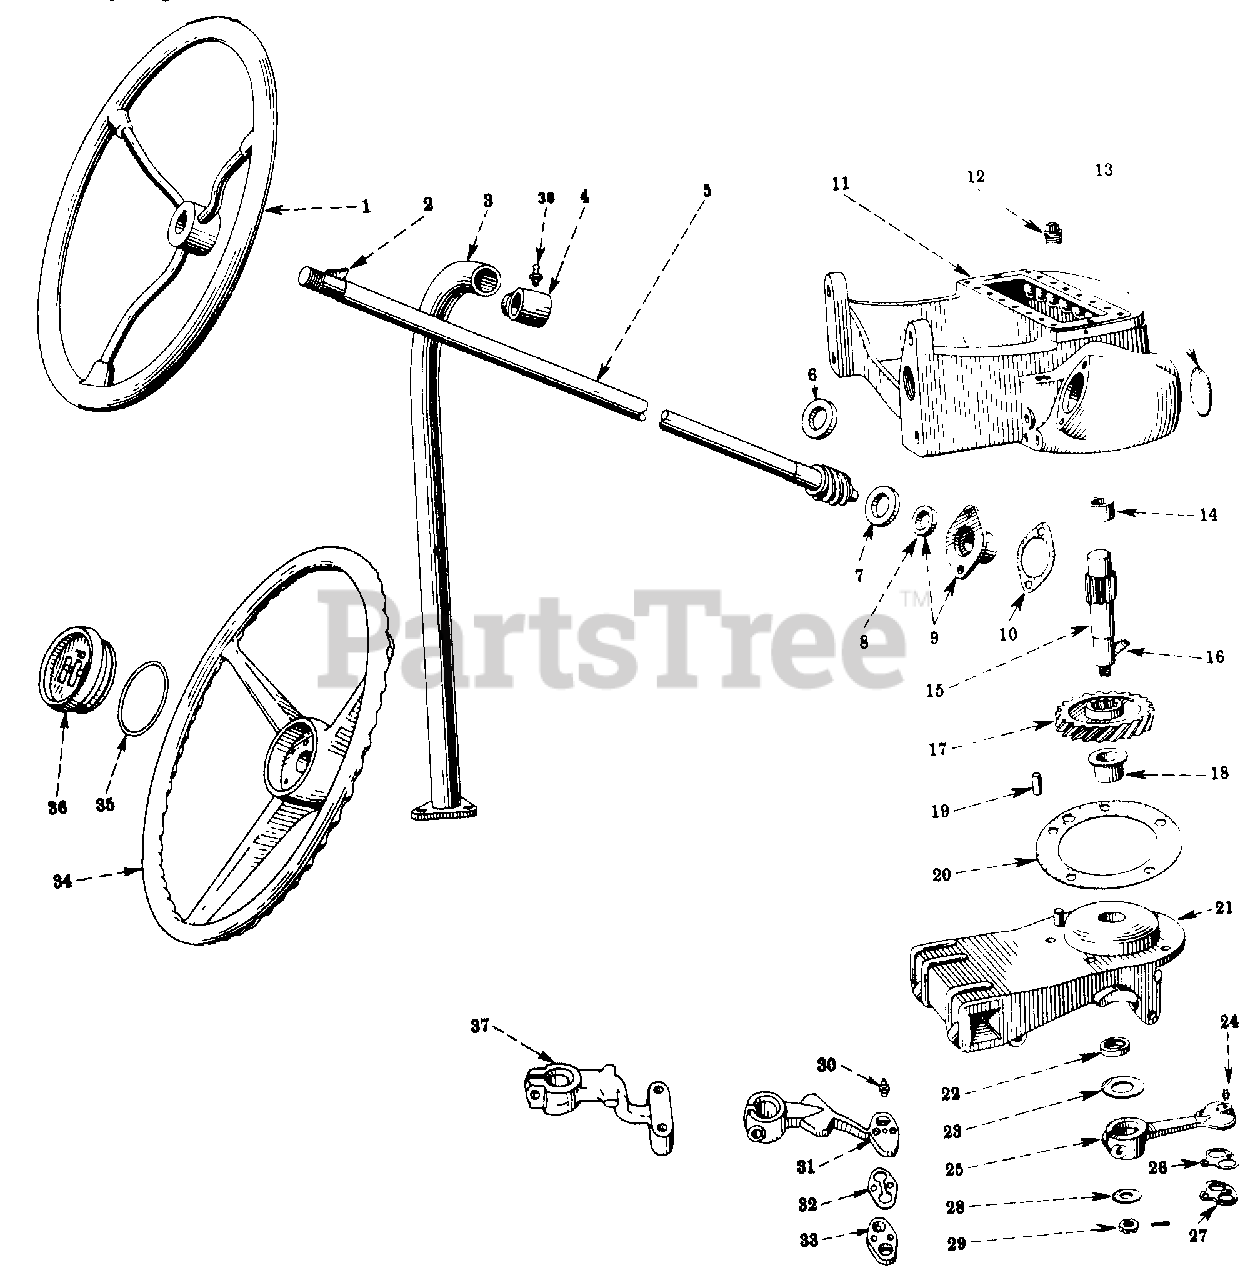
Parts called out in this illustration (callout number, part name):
1	WHEEL, STEERING -15 IN
2	KEY, 1/4 X 7/8 WOODRUFF TYPE A
3	ARM ASSY, STEERING SHAFT SUPPORT
4	BRACKET, STEERING SHAFT SUPPORT ARM
5	SHAFT AND WORM
6	WASHER, STEERING SHAFT UPPER THRUST.
7	WASHER, STEERING SHAFT LOWER THRUST.
8	SEAL, STEERING SHAFT OIL
9	BEARING, STEERING SHAFT
10	GASKET, STEERING SHAFT BEARING
11	HOUSING ASSY, STEERING GEAR
12	PLUG, STEERING GEAR HOUSING OIL FILTER
13	PLUG, 2-1/4 IN DIAMETER EXPANSION
14	BUSHING, STEERING WORM WHEEL SHAFT UPPER
15	SHAFT, STEERING WORM WHEEL
16	KEY, 3/16 X 1-1/8 WOODRUFF NO.16 NI-STL
17	WHEEL, STEERING WORM - 21 TEETH
18	BUSHING, STEERING WORM WHEEL SHAFT LOWER
19	DOWEL, STEERING GEAR HOUSING BASE
20	GASKET, STEERING GEAR HOUSING BASE
21	BASE ASSY, STEERING GEAR HOUSING
22	SEAL, STEERING WORM WHEEL SHAFT OIL
23	WASHER, STEERING WORM WHEEL SHAFT THRUST
24	FITTING, 1/4-28 NS TAPER STR LUB
25	ARM, STEERING GEAR
26	SHIM, STEERING GEAR ARM PLATE LIGHT
27	PLATE, STEERING GEAR ARM
28	WASHER, STEERING GEAR ARM RETAINER
29	NUT, STEERING WORM WHEEL SHAFT
30	FITTING, 3/16 STR DRIVE TYPE LUB
31	ARM, STEERING GEAR
32	SHIM, STEERING GEAR ARM PLATE LIGHT
33	PLATE, STEERING GEAR ARM
34	WHEEL, 18 IN. STEERING
35	O-RING, STEERING WHEEL CAP RETAINING
36	CAP, STEERING WHEEL
37	ARM, STEERING GEAR
38	FITTING, 3/16 STR DRIVE TYPE LUB
